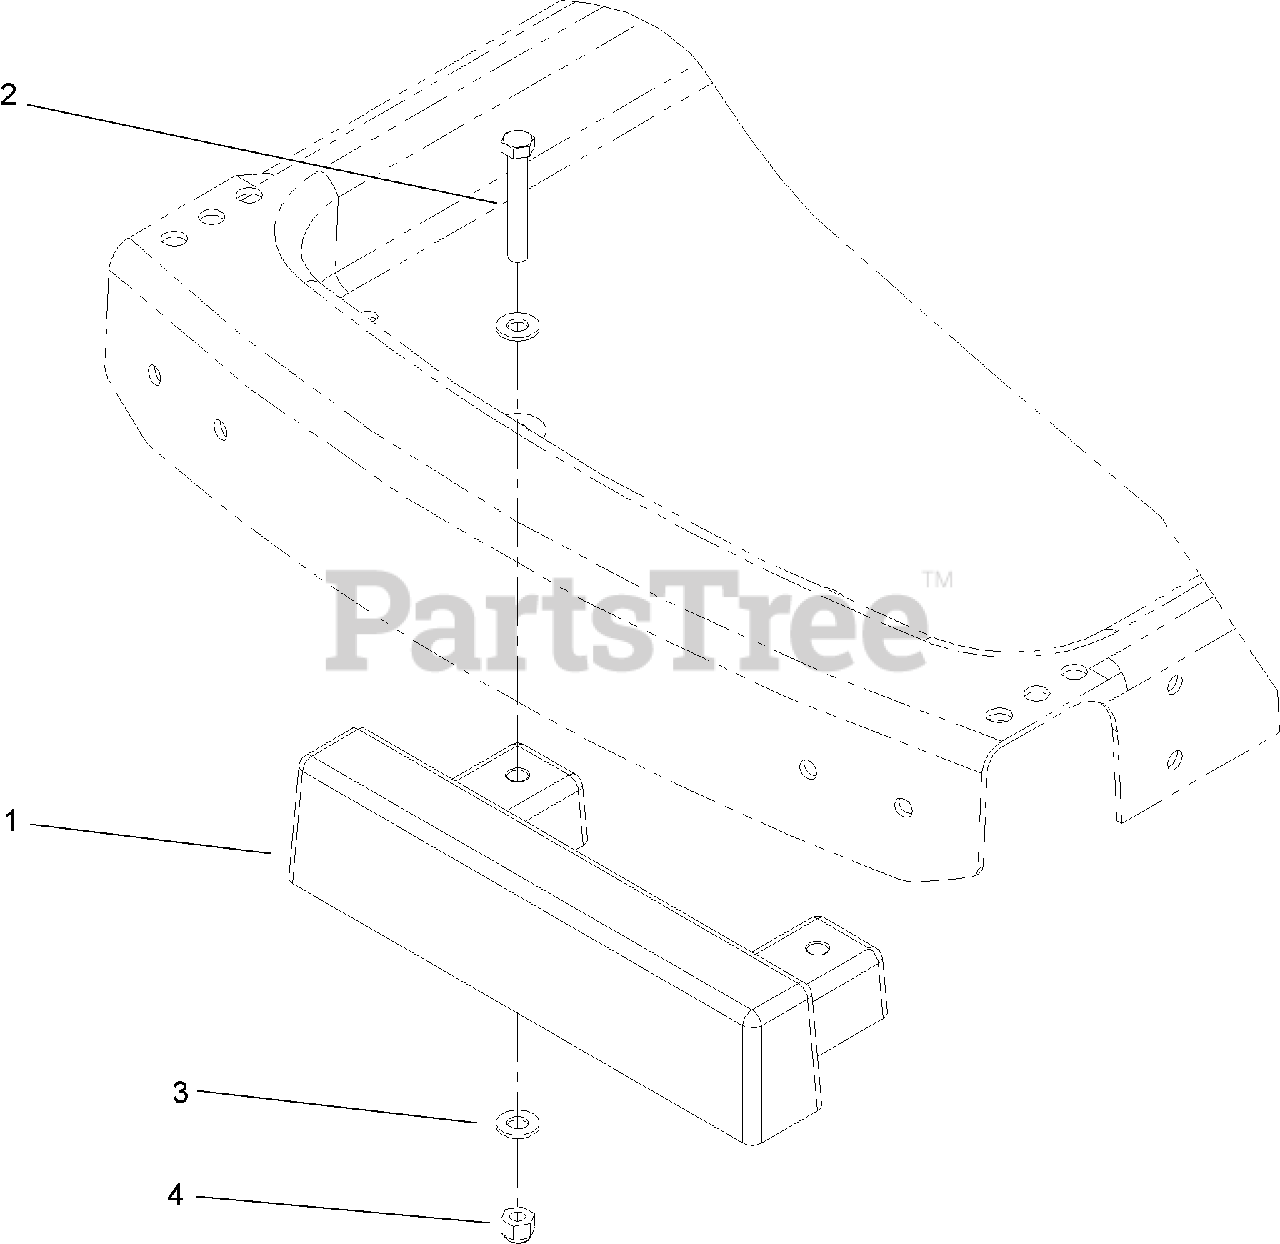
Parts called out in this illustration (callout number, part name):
1	WEIGHT-BAGGER
2	SCREW-HH
3	WASHER-FLAT
4	NUT-LOCK, NI
